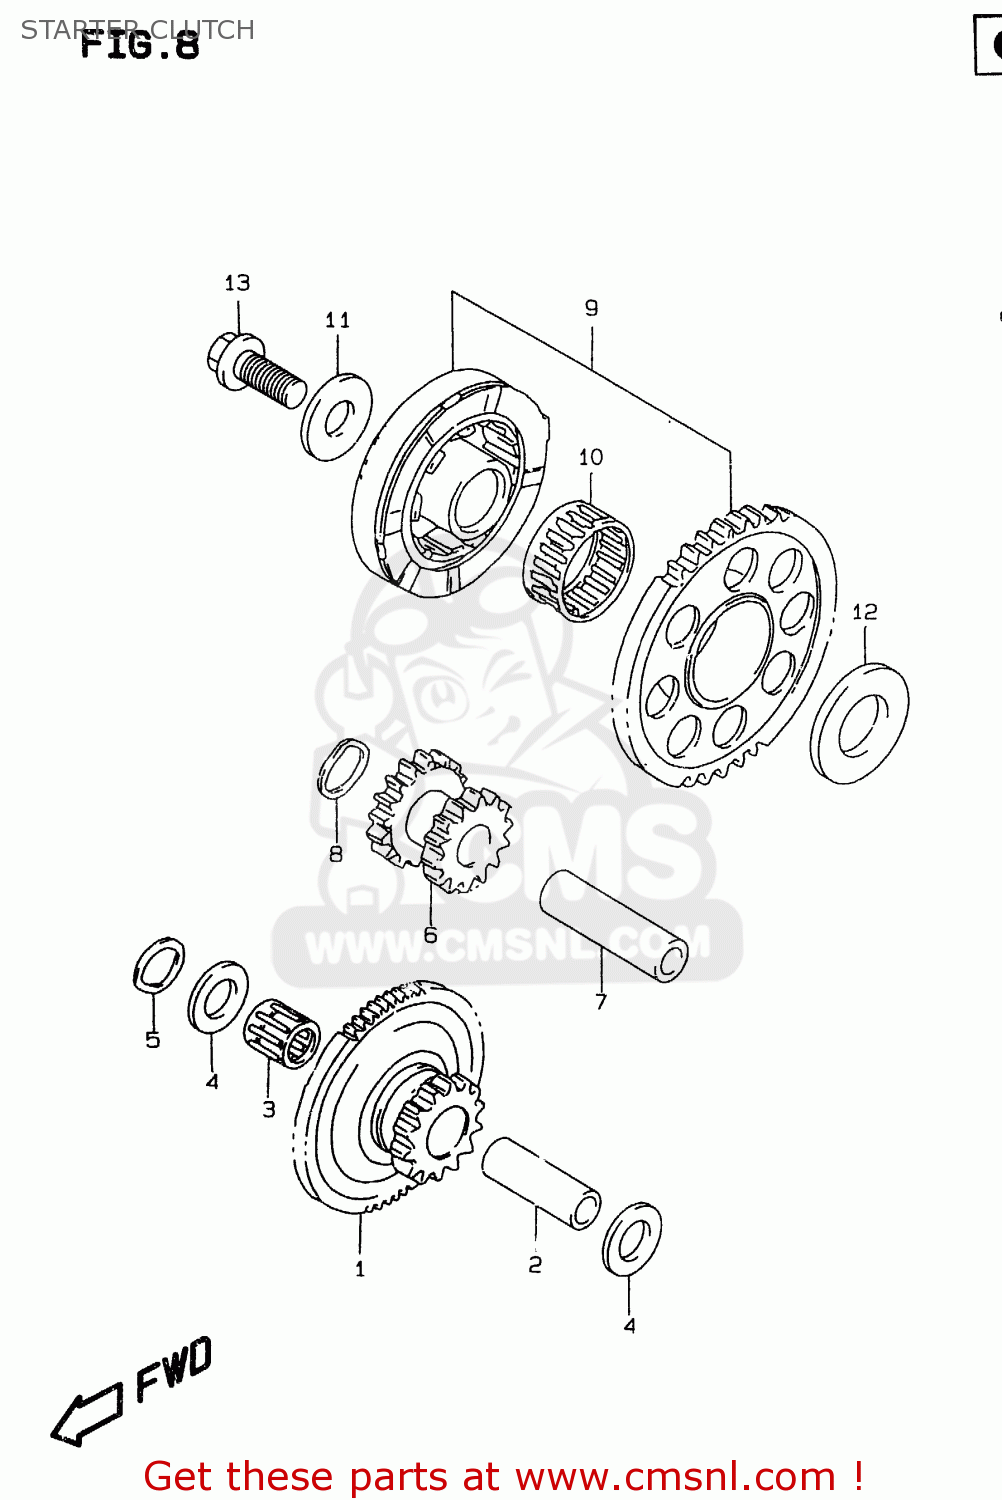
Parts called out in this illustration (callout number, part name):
1	GEAR,STARTER IDLE NO.1
2	PIN,PISTON
3	BEARING(12X16X16)
4	WASHER
5	WASHER
6	GEAR,STARTER I
7	PIN ,PISTON
8	WASHER
9	CLUTCH SET,STARTER
10	BEARING(28X34X16.8)
11	WASHER
12	WASHER
13	BOLT(10X23)
